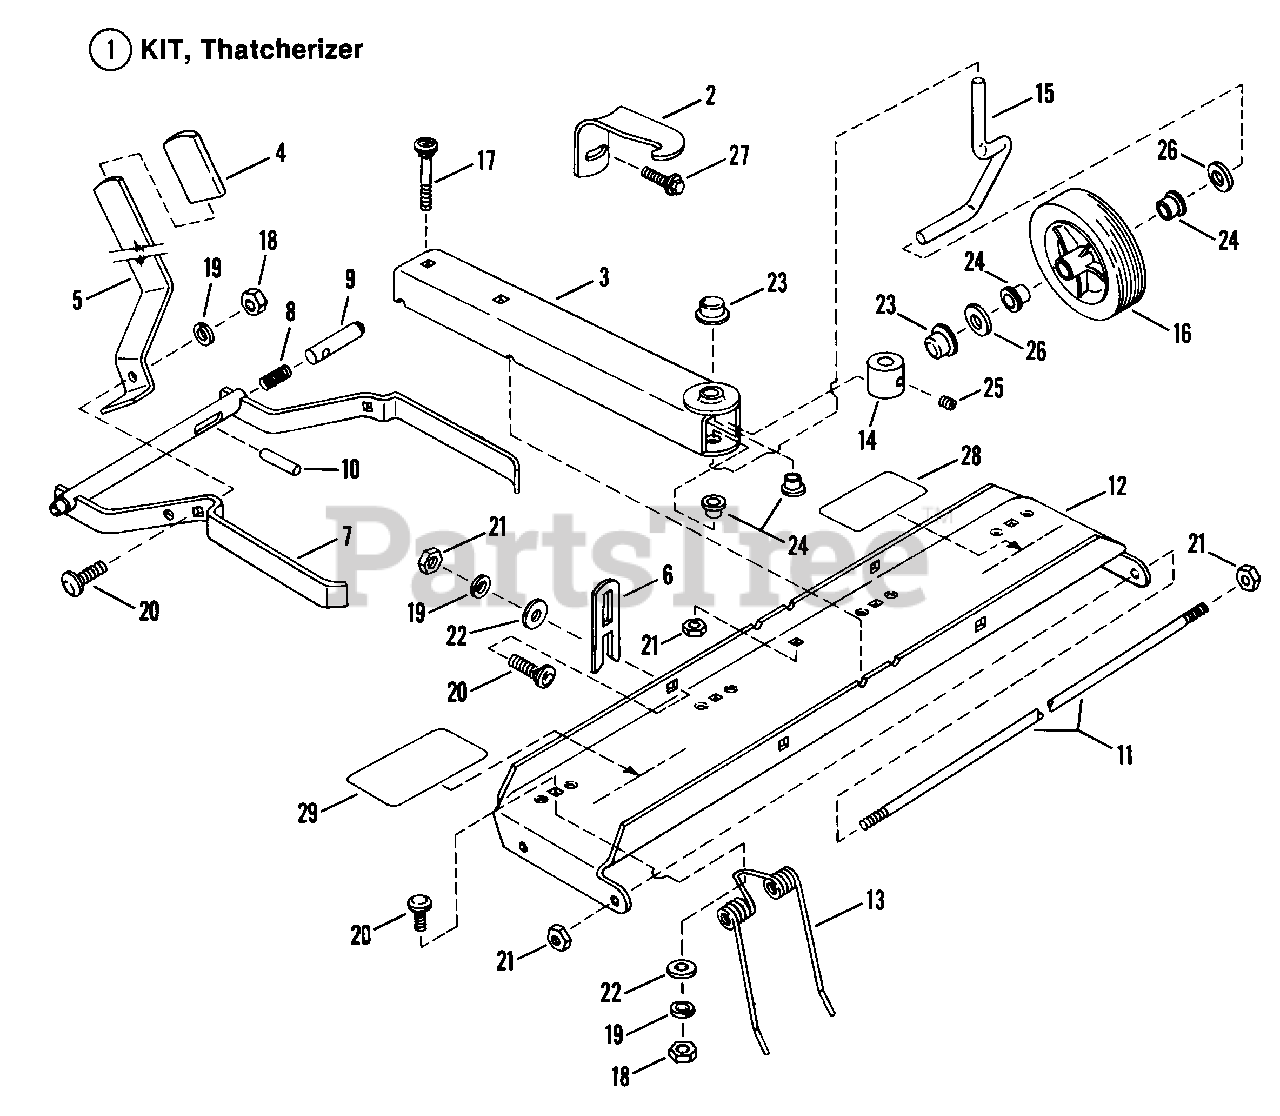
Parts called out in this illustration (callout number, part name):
1	KIT, Thatcherizer
2	BRACKET, Transport Lock
3	SUPPORT, Wheel Assembly
4	GRIP, Handle
5	HANDLE, Lift
6	STRAP, Frame Mount
7	FRAME, Thatcherizer
8	SPRING, Compression
9	PIN, Locking
10	ROLL-PIN
11	ROD, Tine Retainer
12	TRAY, Tine (28")
13	SPRING, Tine Thatching
14	BUSHING
15	AXLE, Wheel
16	WHEEL, 7"
17	CARRIAGE BOLT, 1/4-20x2 1/2"
18	NUT, 5/16-18 Hex
19	LOCKWASHER, 5/16 Split
20	CARRIAGE BOLT, 5/16-18x1"
21	LOCKNUT, 1/4-20 Hex
22	WASHER, Reinforcing
23	PUSH-NUT, 1/2"
24	BEARING, Nyliner, Snap-In
25	SET-SCREW, 5/16-18x1/4" Slotted
26	WASHER, 1/2" SAE
27	SCREW, 5/16-18x3/4" Hex Head Self-Tapping
28	DECAL, Instruction
29	DECAL, Thatcherizer
